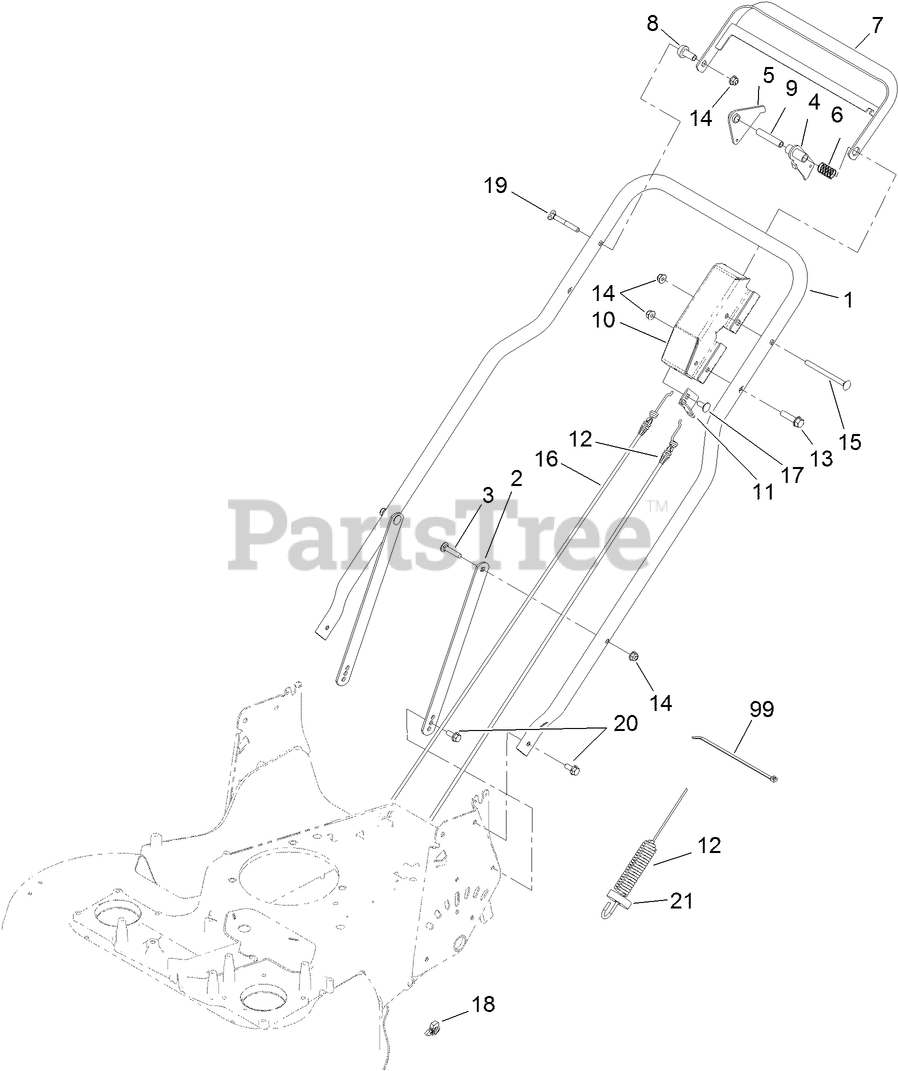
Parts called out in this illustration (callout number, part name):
2	SUPPORT-HANDLE
3	BOLT-CARR
4	BBC LEVER ASM
5	LEVER-TRACTION
6	SPRING-CONTROL
7	BAR-CONTROL
8	SPACER-SUPPORT
9	SPACER-BRACKET, CONTROL
10	BRACKET-CONTROL
11	BRACKET
12	CABLE-BRAKE
13	SCREW-HWH
14	NUT-HF, NI
15	SCREW-CARR
16	CABLE-TRACTION
17	SCREW-CARR
18	CLIP-CONDUIT
19	SCREW
20	SCREW-HHF
21	WASHER
99	TIE-CABLE
